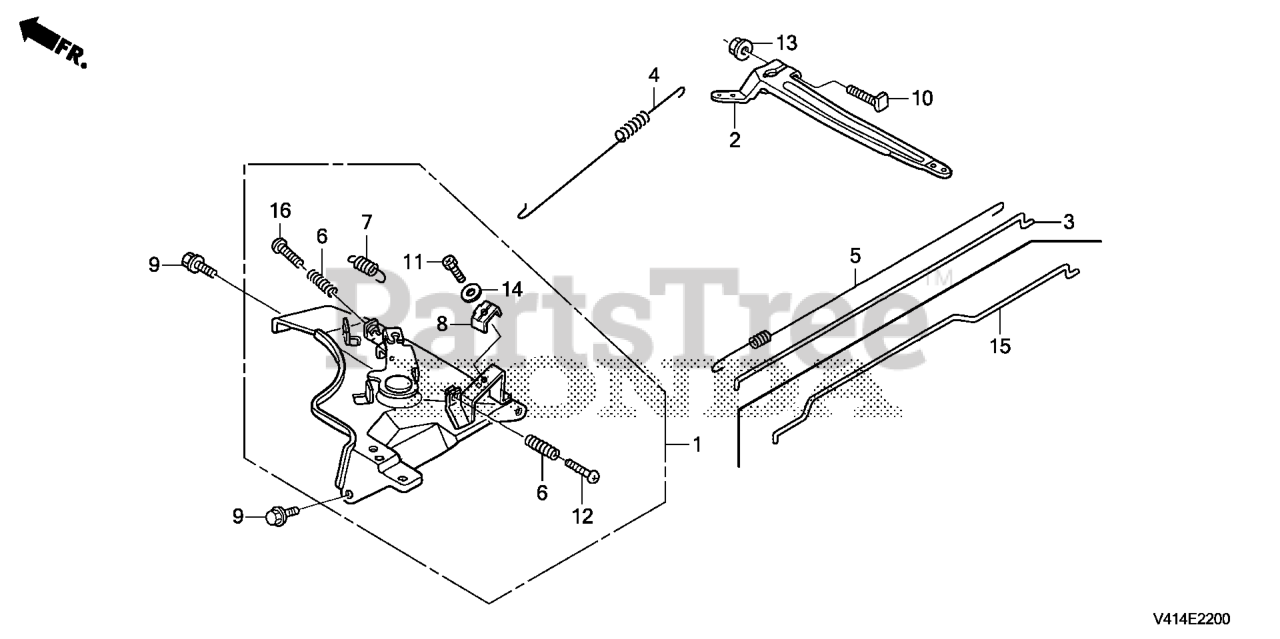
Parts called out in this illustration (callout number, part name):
1	CONTROL ASSY.
2	ARM, GOVERNOR
4	SPRING, GOVERNOR (L=145.0MM) (WIRE DIAMETER 1.0MM)
5	SPRING, THROTTLE RETURN
6	SPRING, CONTROL ADJUSTING Use from Engine SN 2327377.
7	SPRING, CABLE RETURN
8	HOLDER, CABLE
9	BOLT, FLANGE (6X12) (CT200)
10	BOLT, GOVERNOR ARM
11	BOLT, RECESSED (5X22)
12	SCREW, PAN (5X32)
13	NUT, FLANGE (6MM)
14	WASHER, PLAIN (5MM)
15	ROD, GOVERNOR
16	SCREW, PAN (5X35)
